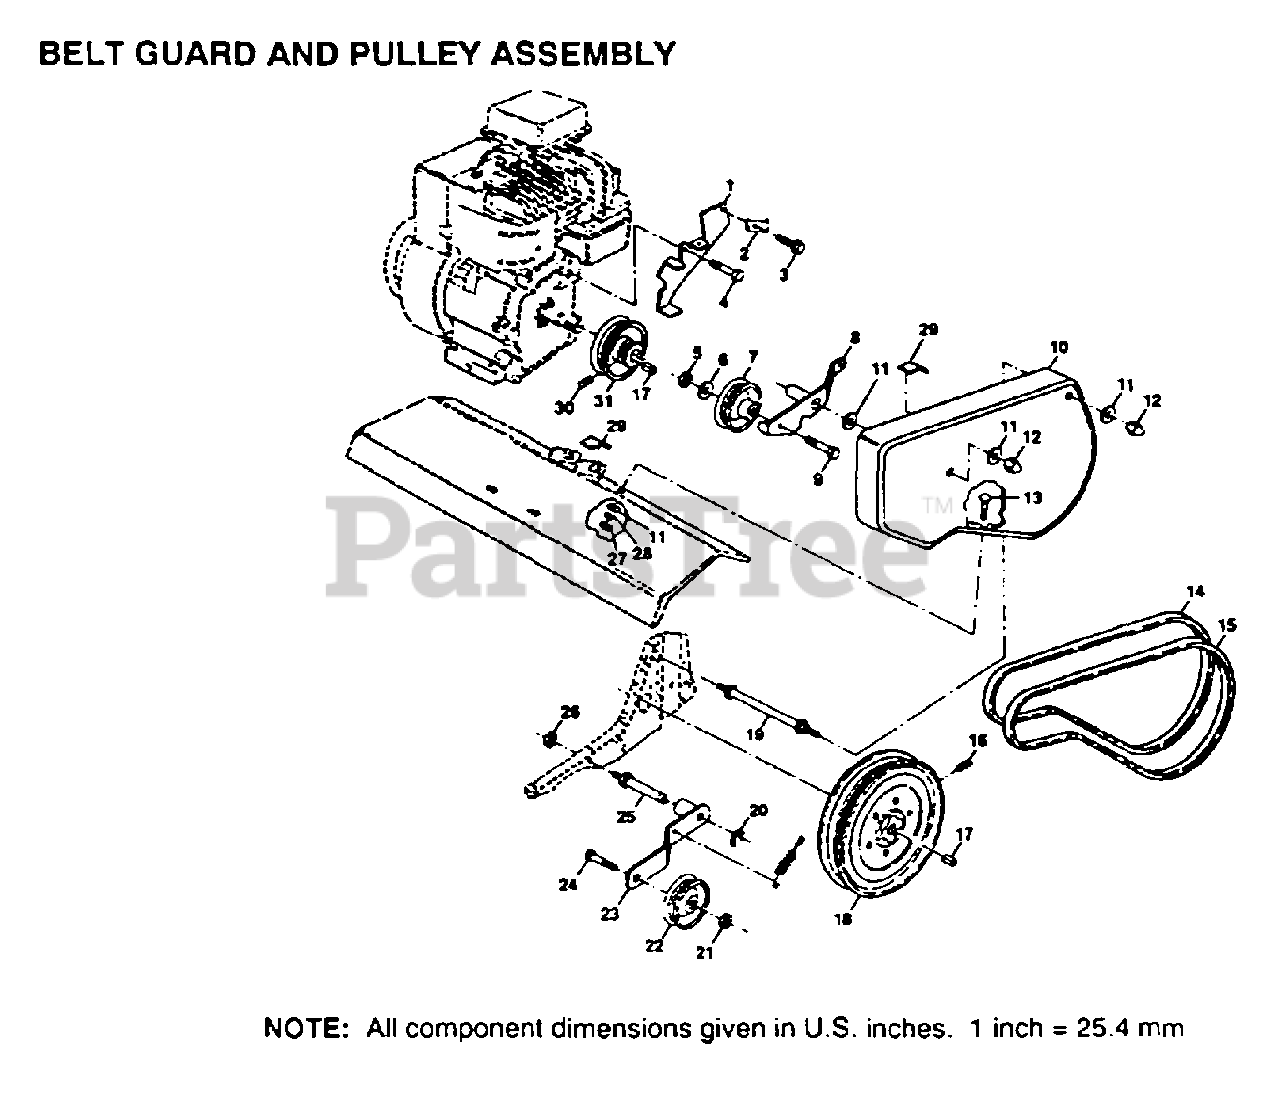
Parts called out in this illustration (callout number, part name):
2	CONDIUT CLIP T
5	NUT.HEX.3/8-16UNC
6	WASHER
7	PULLEY W/SPACER
8	ARM.ASM.REV.IDLER
11	WASHER
12	NUT-CAP TI
13	BOLT T
14	BELT-V
16	SET SCREW
17	KEY T
19	BOLT TI
20	KLIP RING TI
21	NUT
23	IDLER ARM TI
25	SHAFT IDLER TI
26	JAM NUT TI
28	LOCKWASHER
29	PAD IDLER TI
30	SET SCREW
31	ENGINE PULLEY TI
